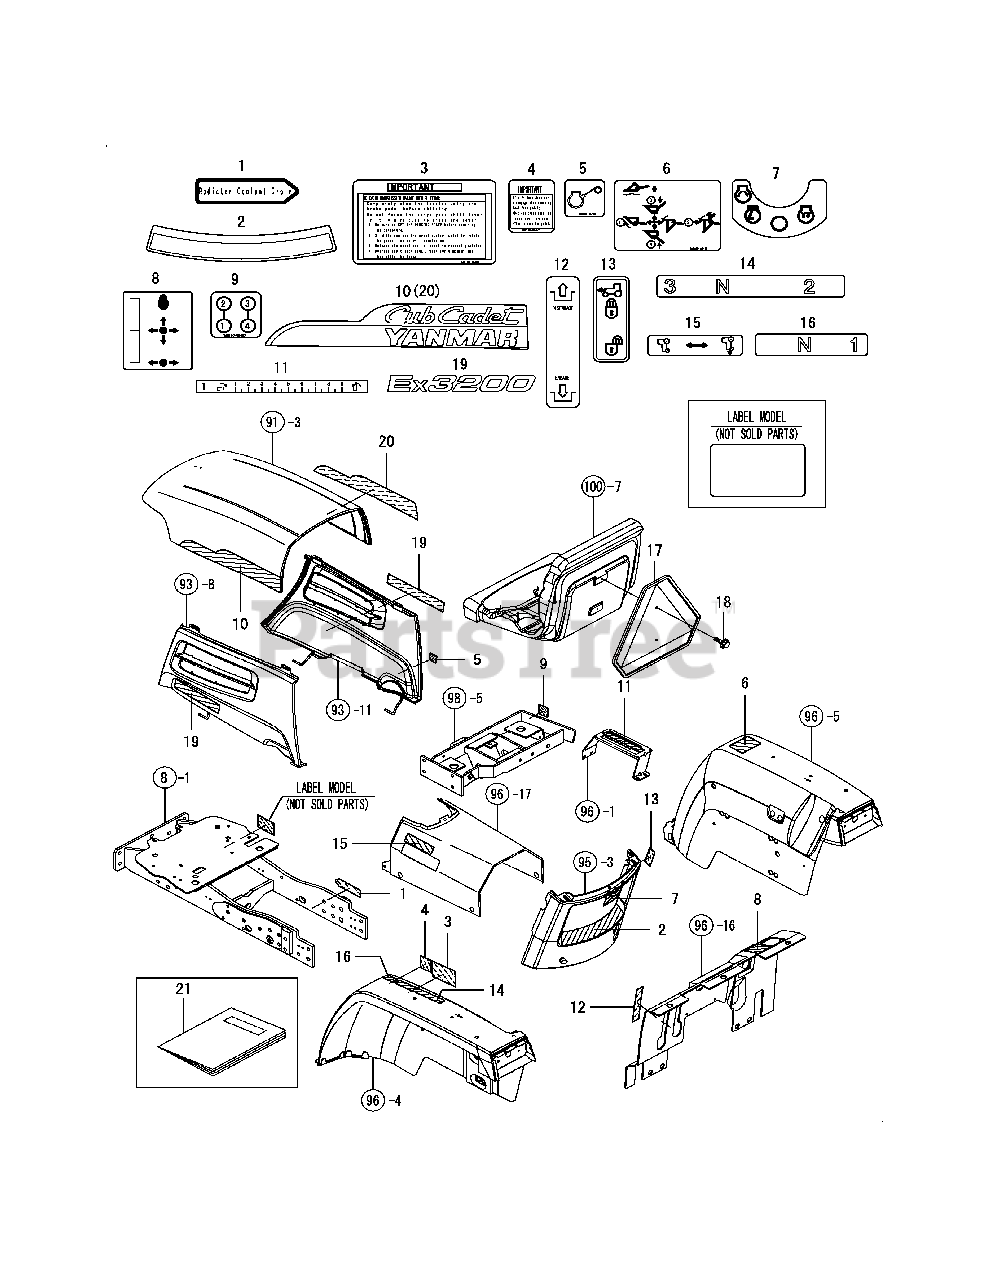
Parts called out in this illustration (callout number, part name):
2	DECAL, COLD START
3	LABEL, IMPORTANT, SHIF
4	LABEL, IMPORTANT, DIFF
6	LABEL, SCV LEVER
7	LABEL, START SWITCH
8	LABEL, SCV LOCK
9	LABEL, SCV COUPLER
14	LABEL, RANGE2-3
17	EMBLEM, SMV CMP
18	BOLT M 6X 20 PLATED
19	LABEL NAME EX3200
21	OPERATOR'S MANUAL
